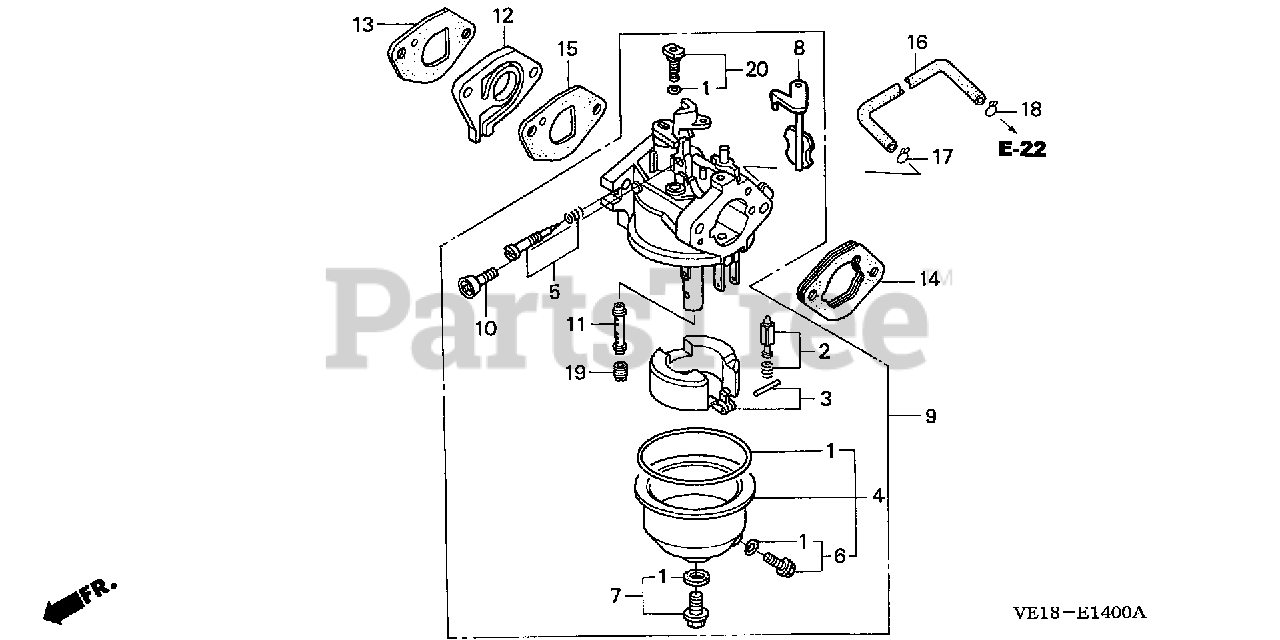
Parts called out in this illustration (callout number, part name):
1	GASKET SET
2	VALVE SET, FLOAT (SEAT NOT INCLUDED)
4	CHAMBER SET, FLOAT
6	SCREW SET, DRAIN
7	SCREW SET
9	CARBURETOR ASSY. (BE52B D)
10	SCREW, THROTTLE STOP
11	NOZZLE, MAIN
12	INSULATOR, CARBURETOR
13	GASKET, CARBURETOR
14	SPACER, CARBURETOR
15	GASKET, CARBURETOR
16	TUBE, FUEL VALVE (170MM)
16	TUBE, FUEL VALVE (175MM)
17	CLIP, TUBE (B8)
18	CLIP, TUBE (B10)
18	CLIP, TUBE (B8)
19	JET, MAIN (#50)
19	JET, MAIN (#52)
19	JET, MAIN (#55)
20	JET SET, PILOT (#35)
